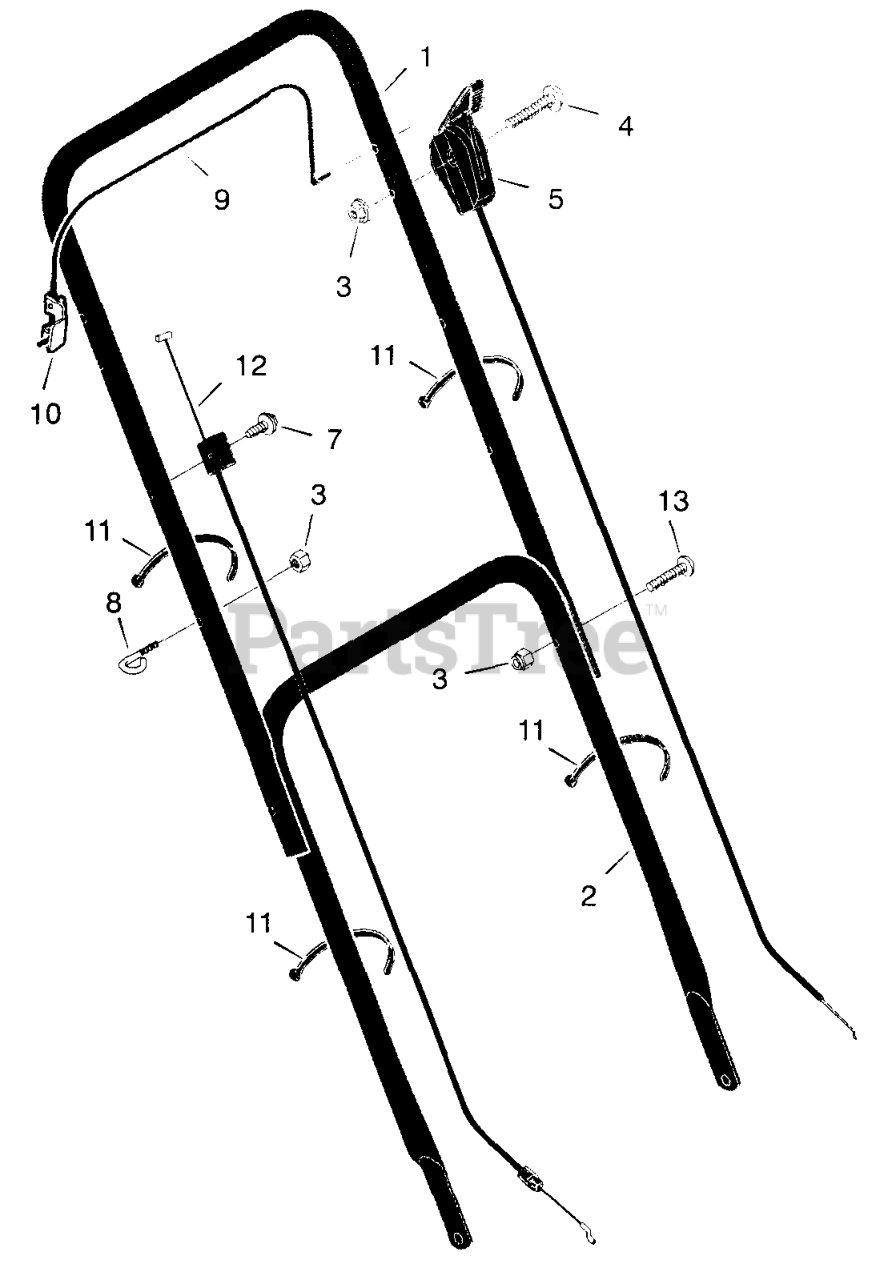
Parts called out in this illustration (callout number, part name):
1	Handle, Upper (Black)
2	Handle, Lower (Black)
3	Locknut
5	Throttle Control
8	GUIDE, ROPE
9	Lever, Engine Stop
10	Bracket, Stop Lever
11	Fastener, Cable
12	Engine Stop Cable
